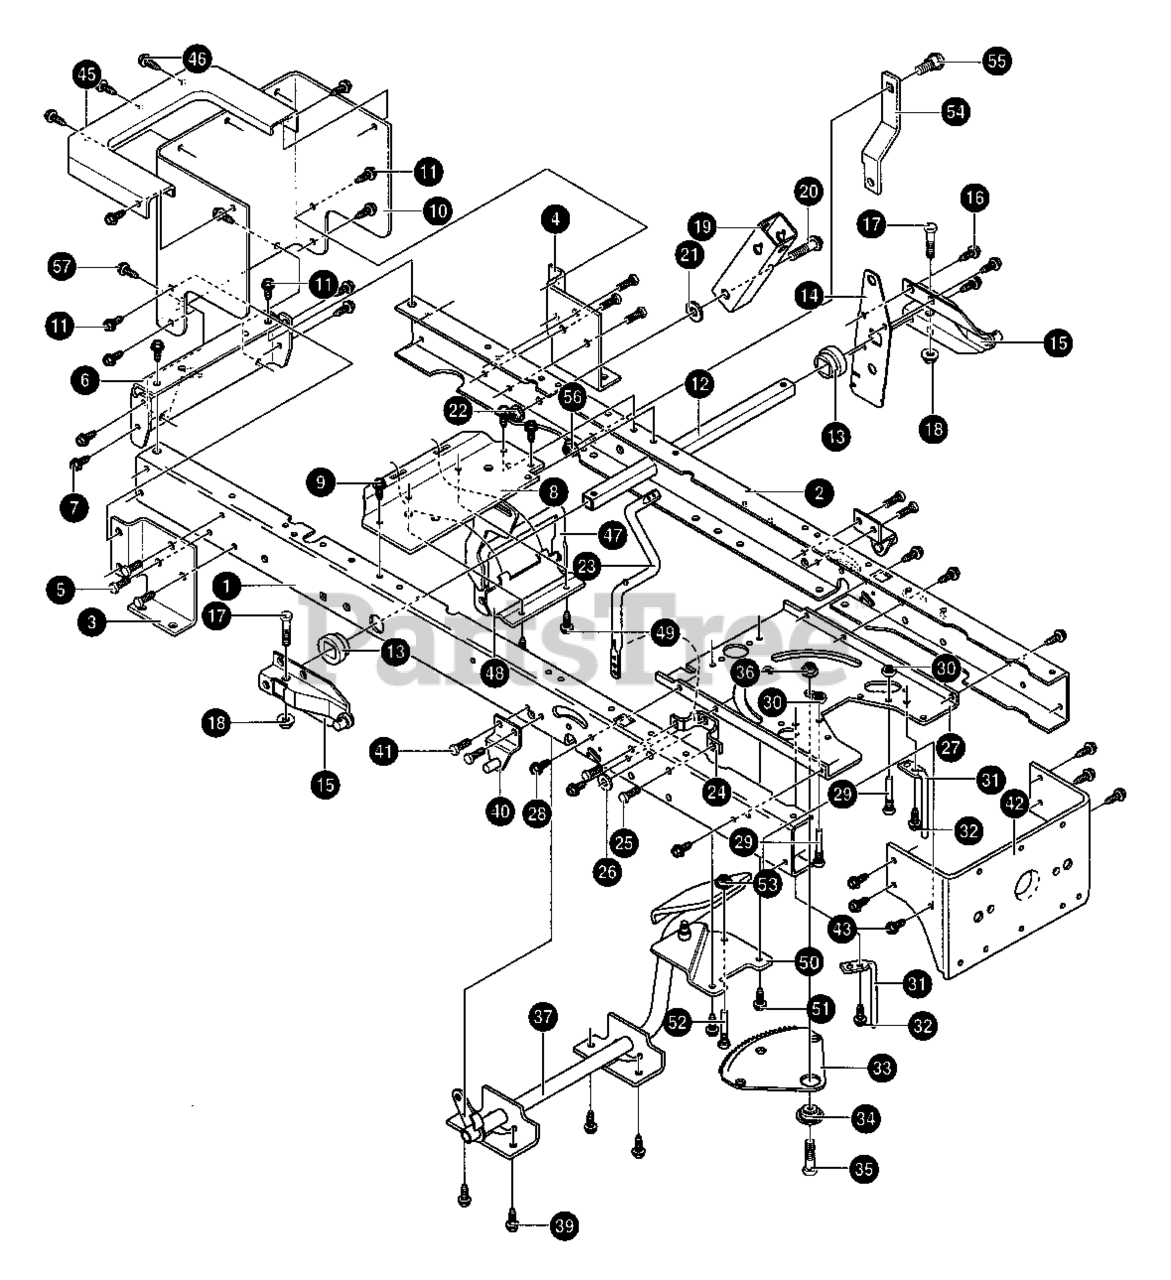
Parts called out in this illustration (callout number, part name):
1	FRAME, RAIL RH
2	FRAME, RAIL LH
3	BRACKET, TRANSAXLE RH
4	BRACKET, TRANSAXLE LH
5	SCREW, 5/16-18 x 0.75
6	HITCH PLATE
7	SCREW, 5/16-18 x 0.75
8	BRACKET, IDLER SUPPORT
9	SCREW 5/16-18X.75
10	PLATE, REAR
11	SCREW, 5/16-18 x 0.75
12	TUBE, LIFTER
13	BUSHING, LIFT TUBE
14	PLATE-LIFT ARM
15	ASSY LIFT ARM LEVER
16	SCREW, 5/16-18 x 0.50
17	SCREW, 5/16-24 x 1.25
18	NUT, 5/16-24
19	BRACKET, PIVOT
21	FLATWASHER
22	NUT, 3/8-16
23	CRANK, PTO (DRILLED)
24	BRACKET, BELLCRANK
25	SCREW, 5/16-18 x 0.75
26	FLATWASHER
27	PLATE, STEERING MOUNT
28	SCREW, 5/16-18 x 0.75
29	SCREW GUIDE 5/16-18
30	NUT, 5/16-18
31	ROD, BELT GUIDE
32	SCREW
33	SECTOR GEAR
34	BEARING, SECTOR GEAR
35	CAPSCREW, Hex Head, 5/16-18 x 1
36	NUT, 5/16-8
37	ASSEMBLY, BRAKE LEVER
39	SCREW, 5/16-18 x 0.75
40	BRACKET, SUSPENSION
41	SCREW, 5/16-18 x 0.75
42	BRACKET, HANGER REAR
43	SCREW, 5/16-18 x 0.75
45	TOP, REAR PLATE
46	SCREW 10-24X.5
47	YOKE ASSY
48	CLAMP, TRUNNION PIVOT
49	SCREW, 51/6-18X.75
50	ASSY, IDLER INTERMEDIATE
51	BOLT, 5/16-18X0.5
52	SCREW GUIDE
53	NUT, 5/16-18
54	BRACKET, Torque Strap, LH
55	BOLT, 5/16-18X0.63
56	NUT, 5/16-18
